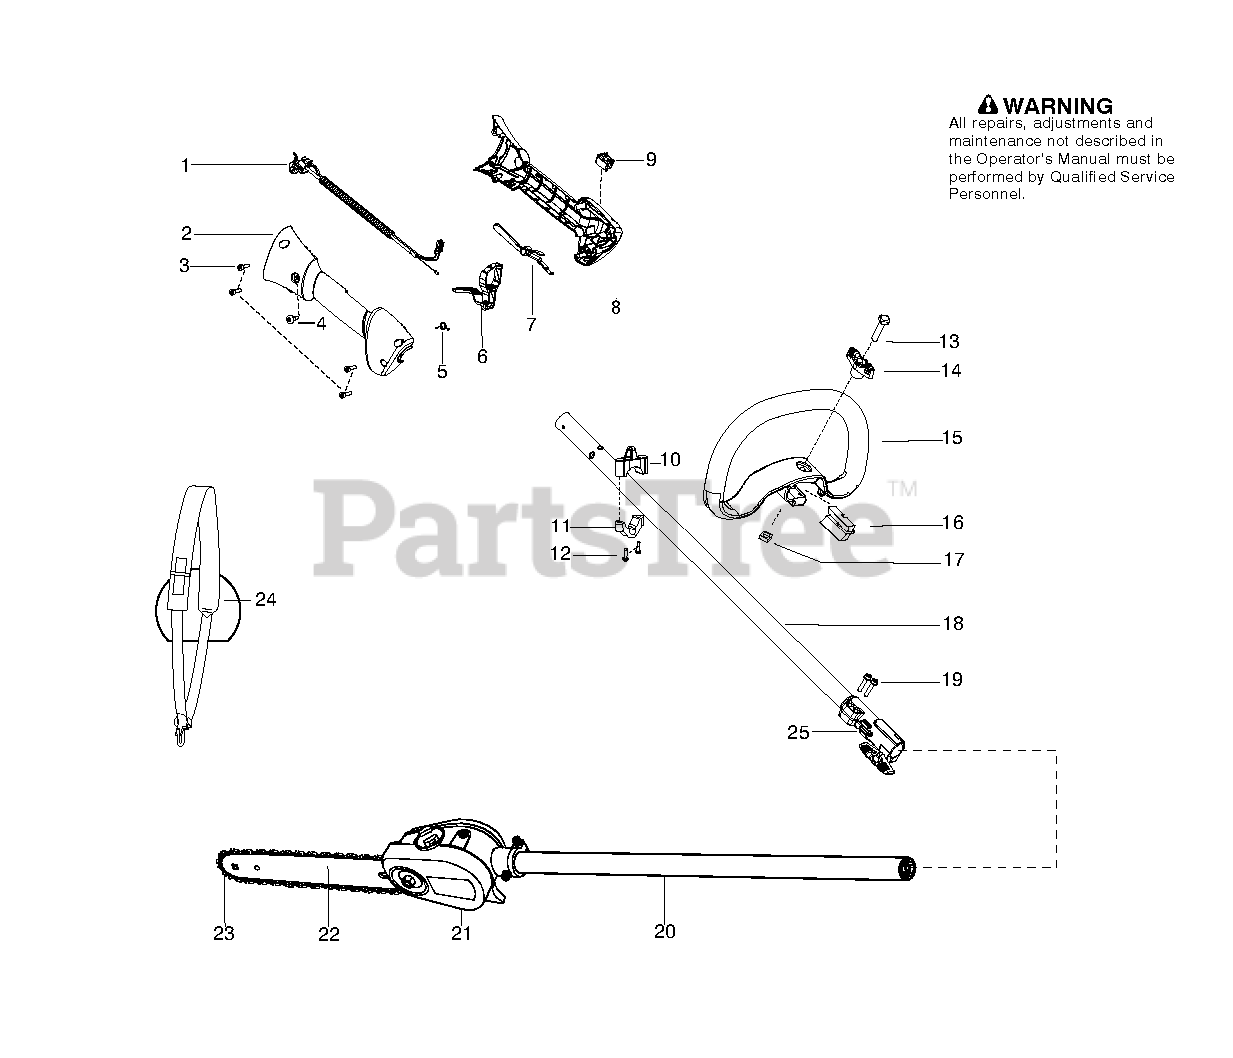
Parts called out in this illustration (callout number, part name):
1	ASSY CABLE / WIRE HARNESS
2	HSG THROTTLE RIGHT HVA
3	SCREW M4 X 1.75 PT 16MM
4	SCREW-10-14 X 1/2 PLASTITE
5	SPRING TRIGGER
6	TRIGGER THROTTLE HVA ORANGE
7	THROTTLE LOCKOUT HVA ORANGE
8	HSG THROTTLE LEFT HVA
9	SWITCH
10	CLAMP HARNESS UPPER
11	CLAMP HARNESS LOWER
13	SCREW M6X50
15	ASSY LOOP HANDLE
16	SPACER PLASTIC
18	DRIVESHAFT
20	KIT DRIVE SHAFT PRUNER
21	CUTTING HEAD ASSY
22	Hl280-45 Guide Bar
23	Chain - 12"
24	Harness - Diagonal with sign
25	CLAMPING SLEEVE
